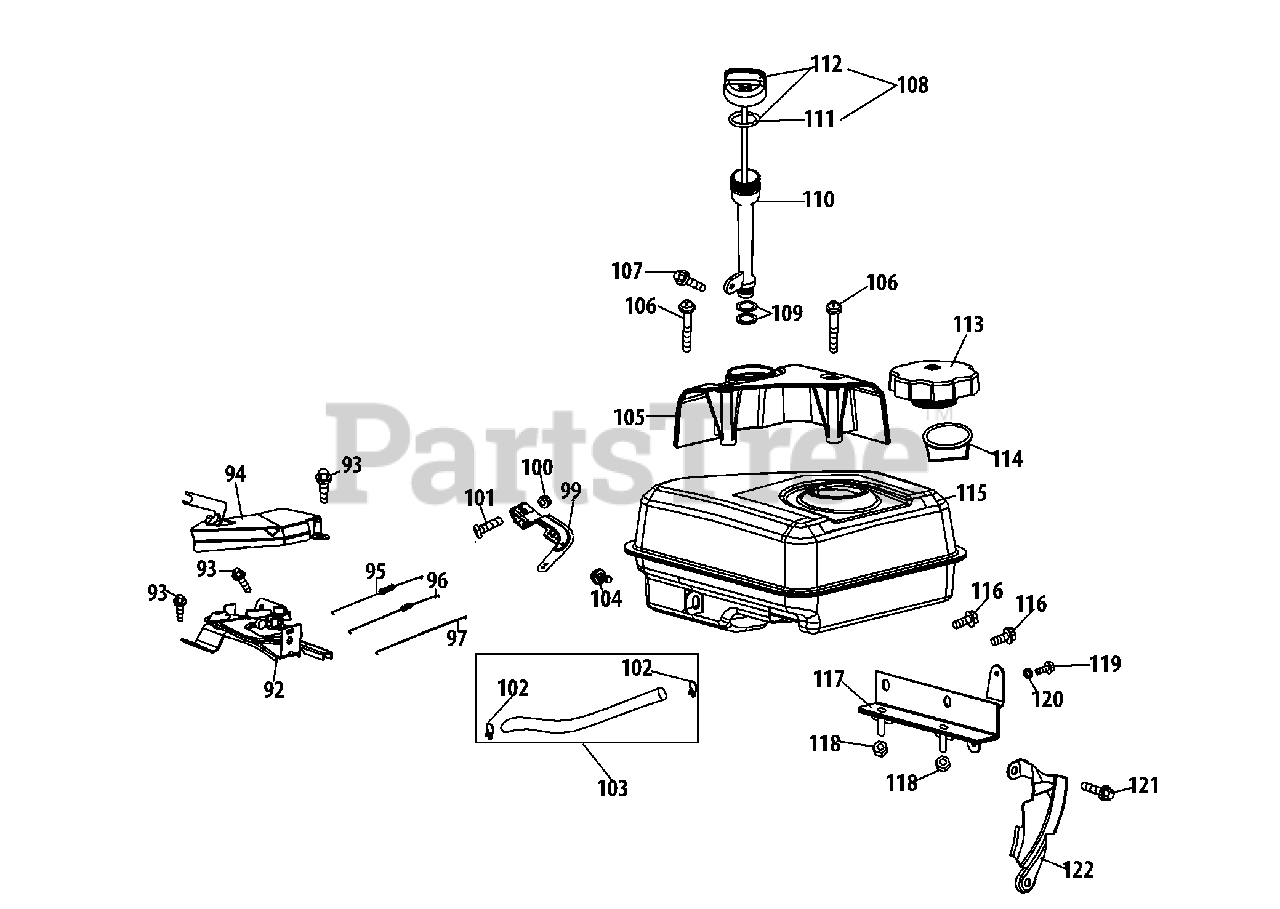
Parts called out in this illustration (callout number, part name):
92	Throttle Bracket
93	Bolt M6×12
94	Governor Linkage Shield
95	Governor Spring
96	Throttle Linkage Spring
97	Throttle Linkage
99	Governor Arm
100	Nut M6
101	Governor Arm Bolt
102	Fuel Hose Clamp
103	Fuel Line Kit
104	Bolt M6×12
105	Dipstick Decoration Cover
107	Bolt M6×12
108	Dipstick Assembly
109	O-Ring
110	Oil Fill Tube Assembly
111	Dipstick O-Ring
112	Dipstick Tube
113	Fuel Cap Assembly
114	Fuel Level Indicator
115	Fuel Tank Assembly
116	Bolt M6×10
117	Switch Housing Mounting Bracket
118	Nut, M6
119	Bolt M4×10
120	Washer 4
121	Bolt M6×20
122	Blower Housing Shield
